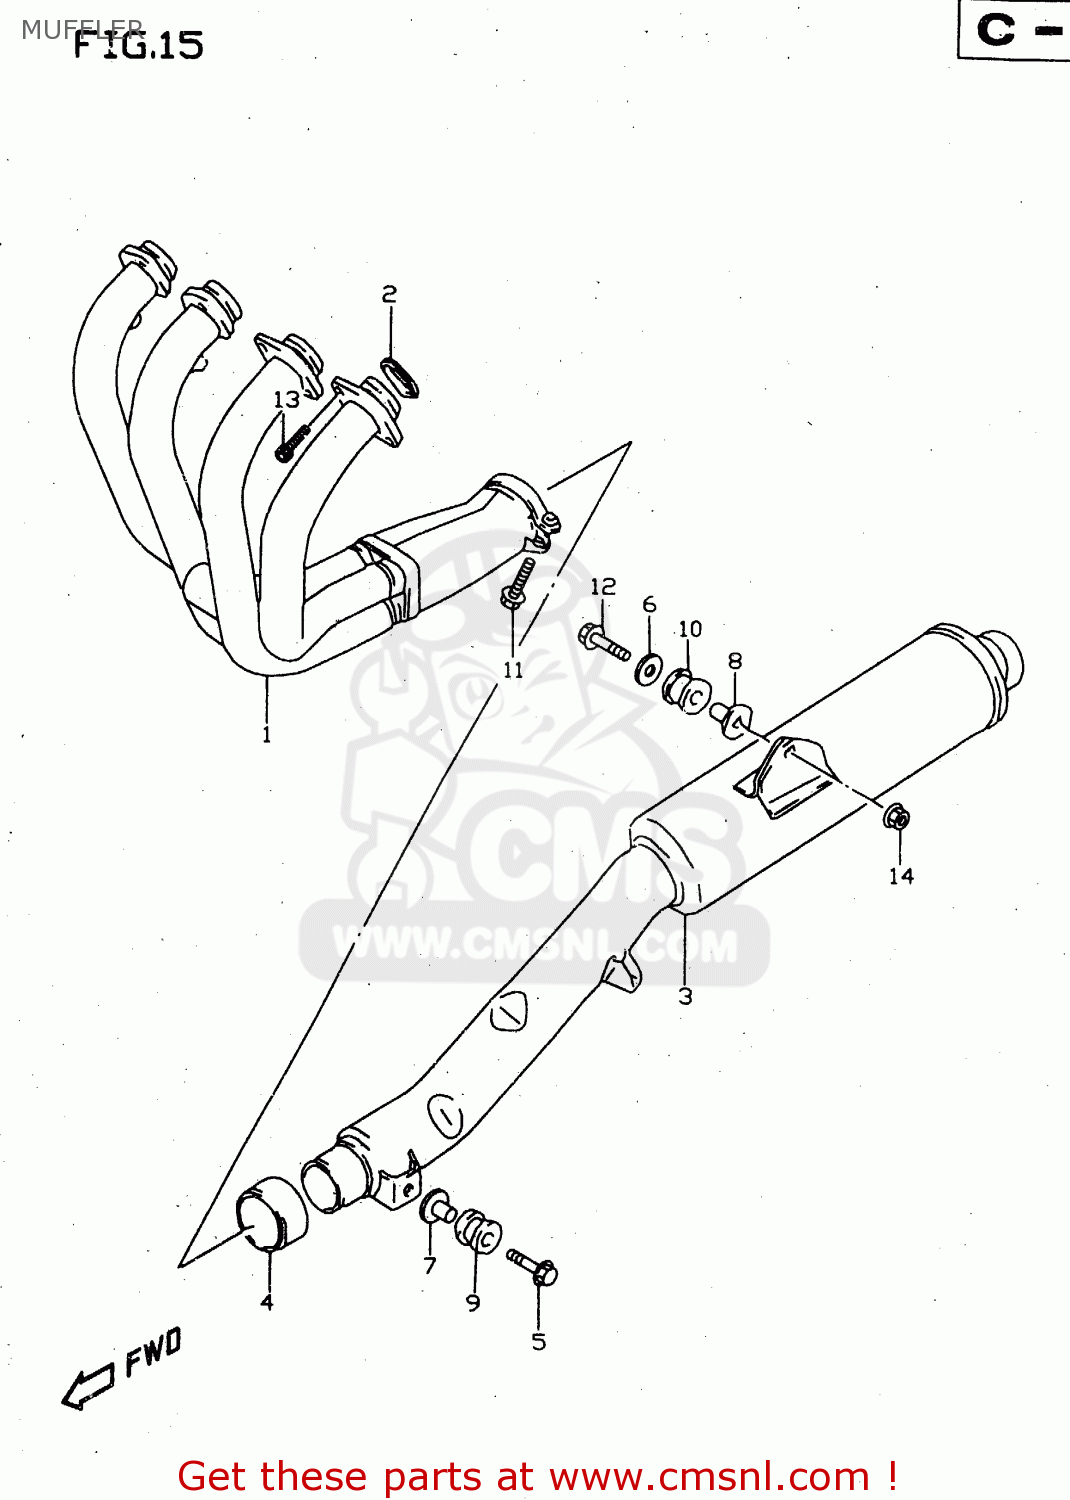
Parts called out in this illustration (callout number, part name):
1	EXHAUST
2	GASKET,EXHAUST (NAS)
3	BODY,MUFFLER
4	CONNECTOR,MUFFLER
5	BOLT 8X40
6	WASHER (8.5X33X1.6)
7	SPACER(8.6X12X24.2)
8	SPACER(8.6X12X27.1)
9	CUSHION
10	CUSHION
11	BOLT
12	BOLT
13	BOLT
14	NUT
